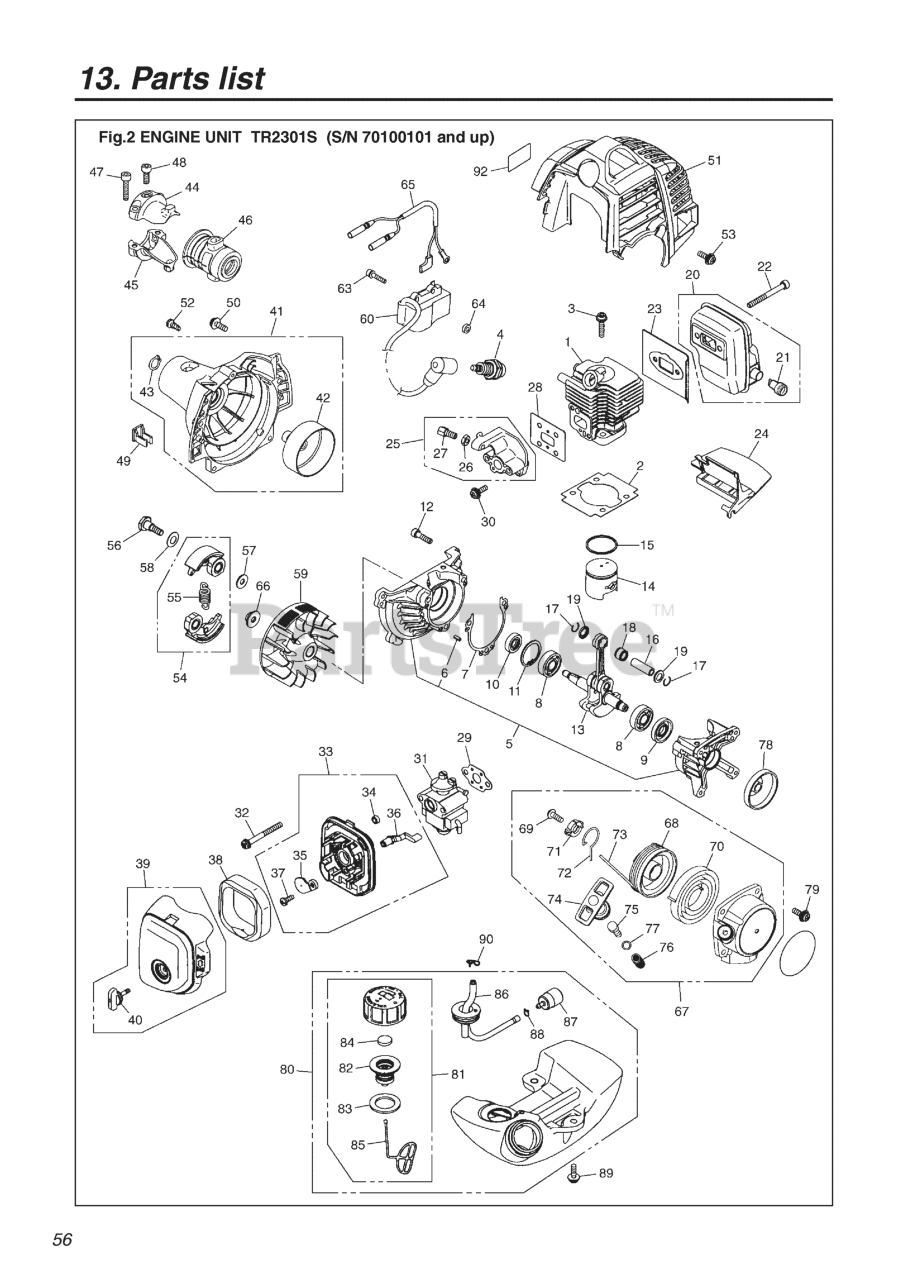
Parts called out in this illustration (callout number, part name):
1	CYLINDER
2	GASKET, BASE
3	BOLT, M5 X 22
4	PLUG (BPMR7A)(RPLS 5933-73110)
5	CRANKCASE-C
6	PIN
7	GASKET, CASE
8	BEARING
9	SEAL
10	SEAL
11	RING, SNAP, M26 X 1.2
12	BOLT, M5 X 20
13	CRANKSHAFT-C
14	PISTON
15	RING, PISTON (RPLS 1850-41210)
16	PIN, PISTON 5x8x26
17	RING, SNAP (RPLS 1101-41320)
18	BEARING (RPLS 1140-41330)
19	WASHER
20	MUFFLER-A
21	ARRESTER
22	BOLT, M5 x 50
23	GASKET
24	PLATE
25	INSULATOR-C
26	NUT, CABLE ADJUSTER
27	SCREW (RPLS 1918-81170)
28	GASKET (RPLS -13120)
29	GASKET (REPLACES -13130)
30	SCREW
31	CARBURETOR-A
32	SCREW (RPLS 0263-30550)
33	BODY ASSY.
34	SLEEVE
35	PLATE, CHOKE
36	LEVER
37	SCREW (REPLACES 50030272)
38	ELEMENT
39	COVER-A
40	KNOB (RPLS -82220)
41	HOUSING ASSY
42	DRUM (REPLACES 4810-31122)
43	RING, SNAP (RPLS 3130-13270)
44	BRACKET (A) (RPLS -31211)
45	BRACKET (B)
46	CUSHION (RPLS -31231)
47	BOLT, M5 X 22
48	BOLT, M5 X 10
49	CLAMP
50	SCREW
51	COVER, ENGINE
52	SCREW, M5 X 10
53	SCREW
54	SHOE COMP.
55	SPRING
56	BOLT
57	WASHER, FLAT (USE 182303)
59	ROTOR
60	COIL
63	BOLT, M4 x 20
64	SPACER (RPLS -71260)
65	CORD COMP.
66	NUT, M6
67	RECOIL-A
68	REEL
69	SCREW
70	SPRING
71	COLLAR
72	ARM
73	ROPE
74	KNOB
75	COLLAR
76	SPRING
77	WASHER
78	PULLEY
79	SCREW
80	TANK-A
81	CAP ASSY (RPLS. 5601-85201)
82	HOLDER - A (RPLS 5601-85230)
83	PACKING
84	FILTER
85	STOPPER
86	PIPE COMPLETE
87	FILTER (RPLS 1850-85300)
88	CLIP (REPLACES 2841-31280)
89	SCREW
90	CLIP
92	LABEL
NI	LABEL, RECOIL
